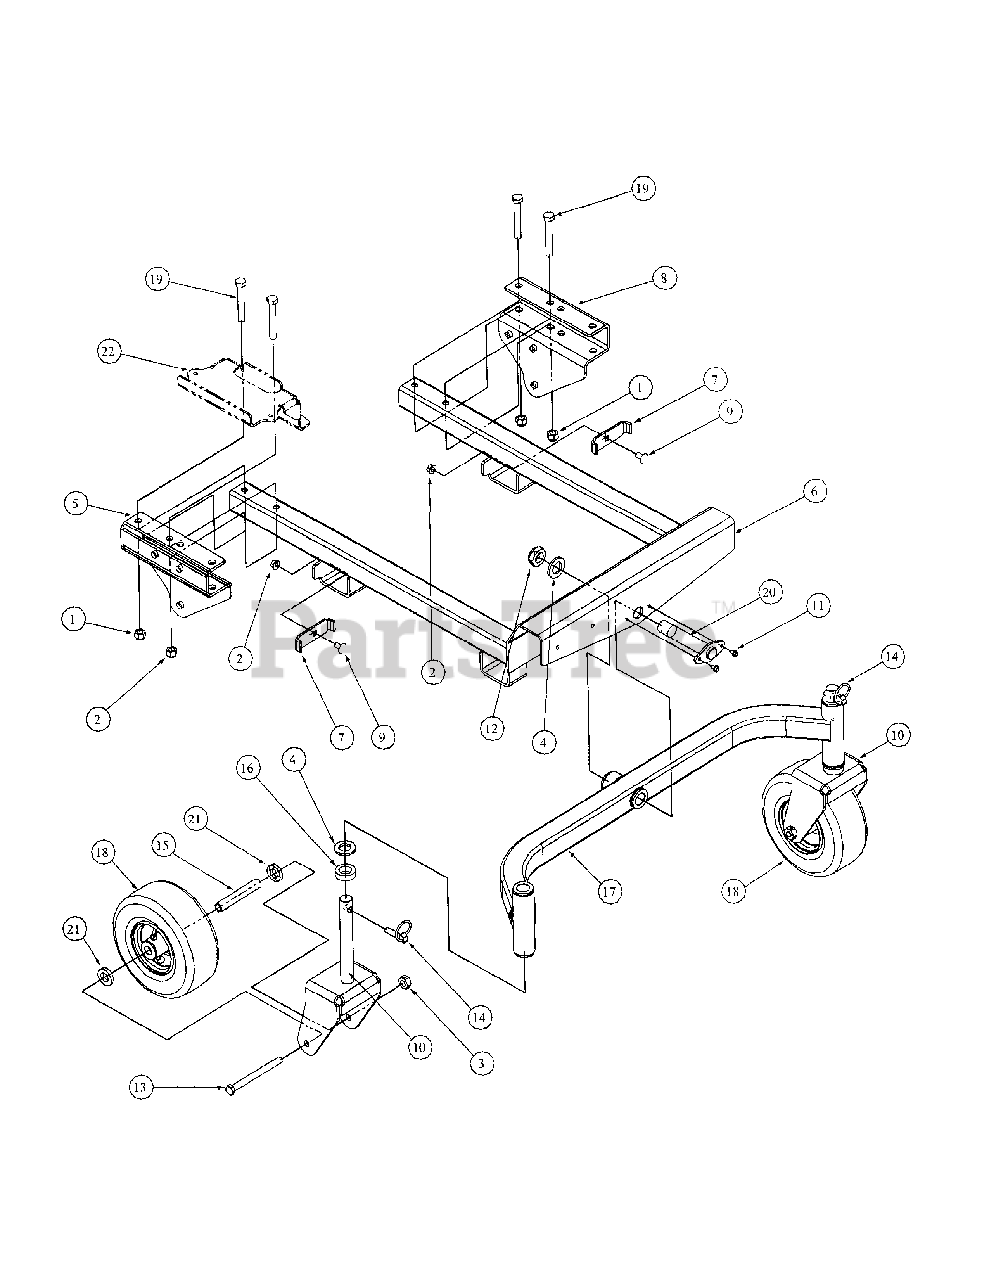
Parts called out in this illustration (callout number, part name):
1	Hex Jam Nut 1/2-13
2	Nut, Hex 3/8-16 Flange Lock
3	Nut, 1/2-20, Center Lock
4	Washer Special
5	Support Brack Frame Right Hand
6	Front Frame Assembly
7	Plate Wear
8	Bracket Support Frame, Left Hand
9	Carrige Bolt, 3/8-16 x .75 LG.
10	Caster Assembly
11	Screw, TT, 1/4-20, 0.500, Hex Index
11	Flange Bearing
12	Nut, Jam, 1.0-14, Insert Lock
13	HHCS, 1/2-20, 5.50
14	Pin, Klik, 1.75 LG
15	Spacer Wheel
16	Spacer, 1.015 ID x 1.62 OD x .50
17	Front Axle Assembly
18	Wheel Assembly 9.0 x 3.50 -4
19	Hex Cap Screw, 1 /2-13 x 3.25
20	Pin Assembly, Plated
21	Spacer, .790 ID x .347 LG
22	Battery Bracket
